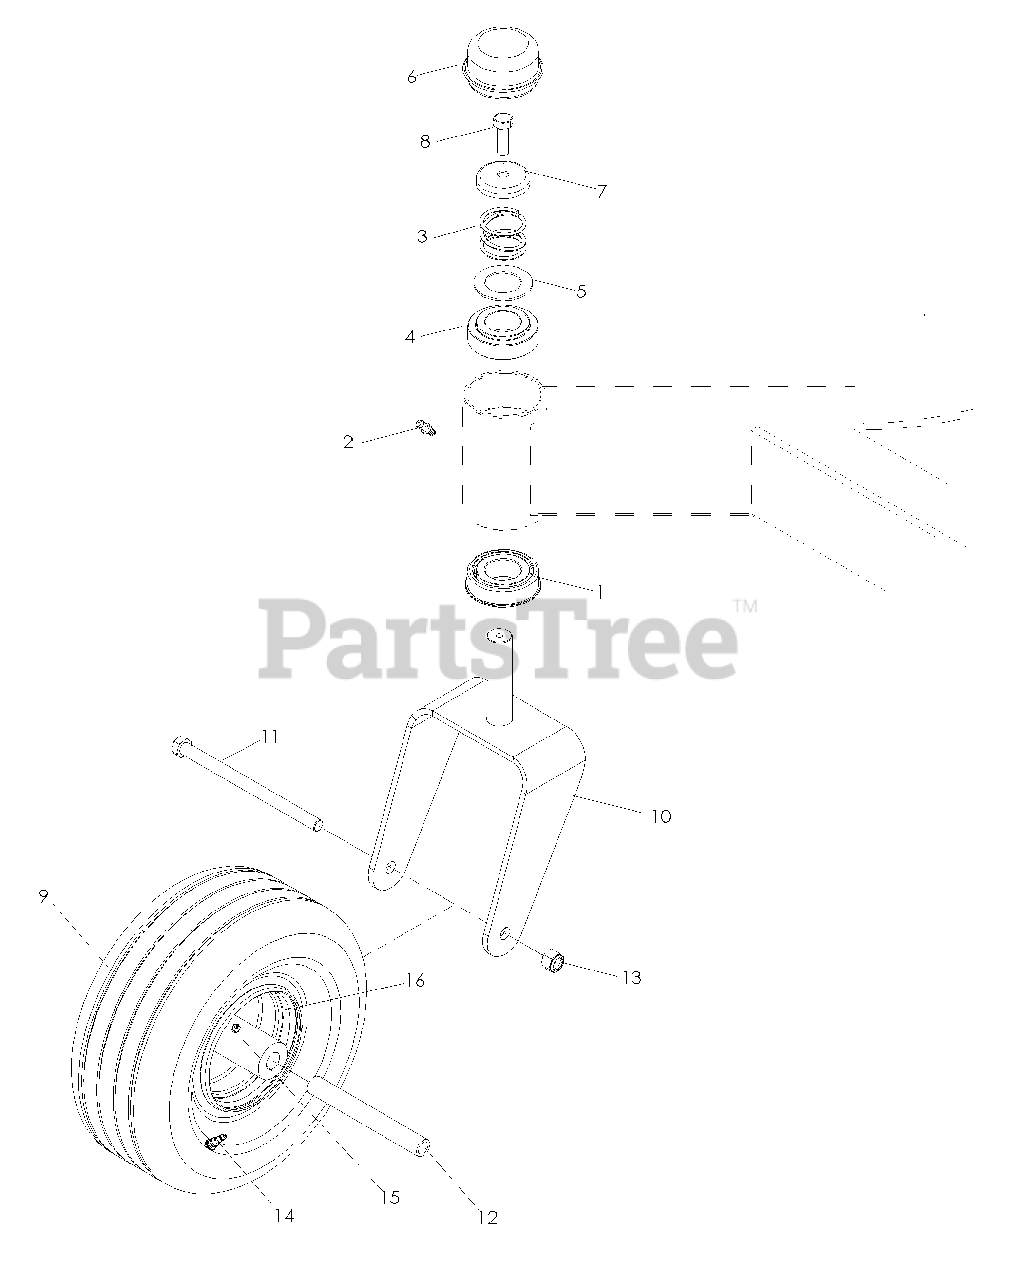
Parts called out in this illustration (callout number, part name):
1	BEARING, FLANGED
2	3/16" DRIVE ZERK
3	SPRING, CASTER
4	BUSHING, CASTER
5	WASHER, 1.025 ID x 1.64
6	GREASE CAP
7	PLUG, CASTER
8	HCS 5/16-18 x 1
9	TIRE ASSEMBLY
10	YOKE, CASTER
11	HCS 1/2-13 x 7 1/2
13	NUT 1/2 HEX NYLOC
16	RIM
